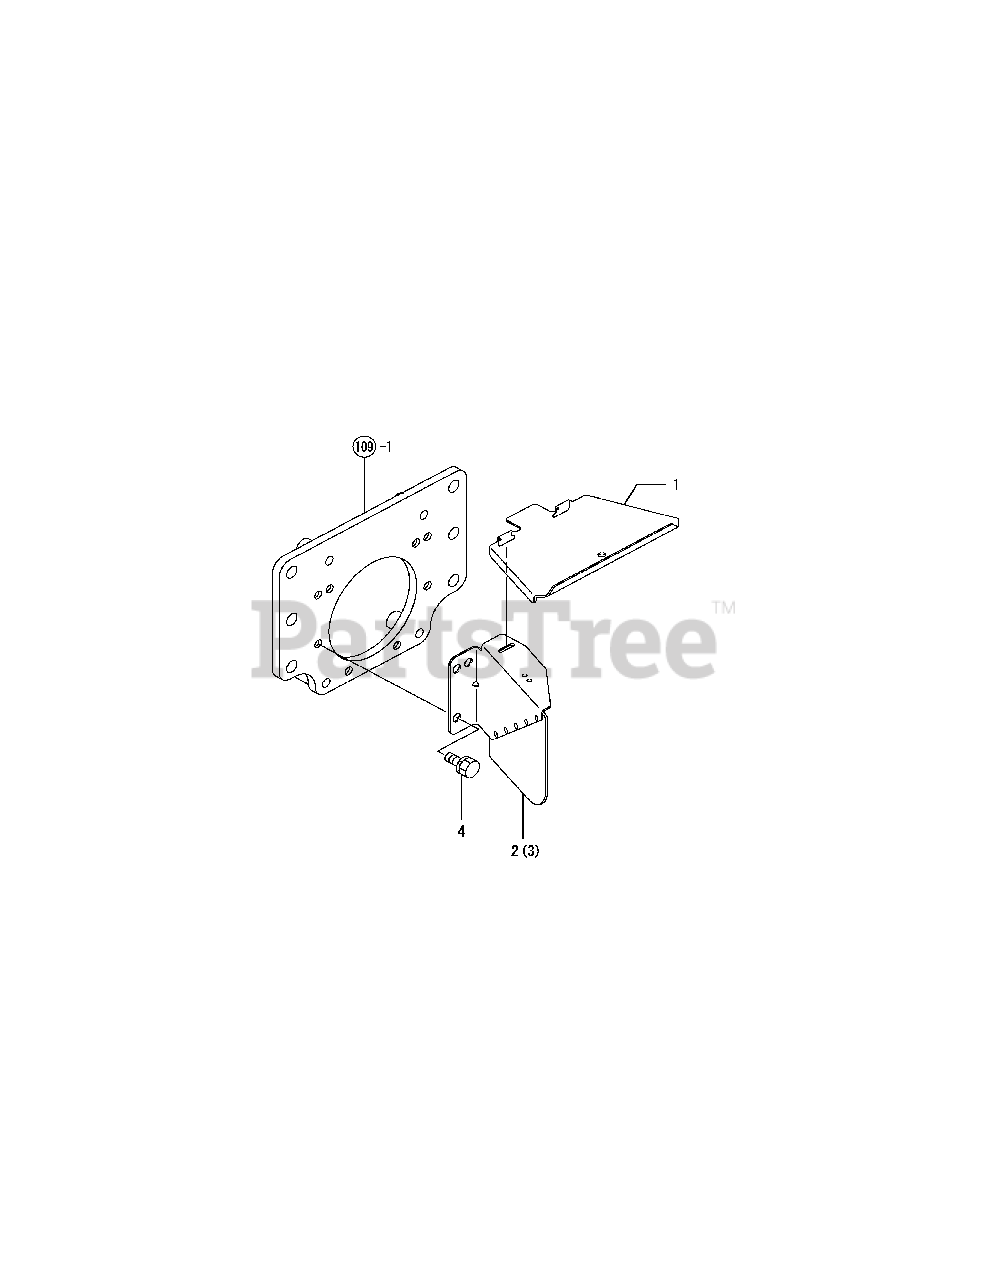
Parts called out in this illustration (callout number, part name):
1	SHIELD, PTO KIT
2	BRACKET L.H., PTO
3	BRACKET,R.H., PTO
4	BOLT W/WASHER M12X20
